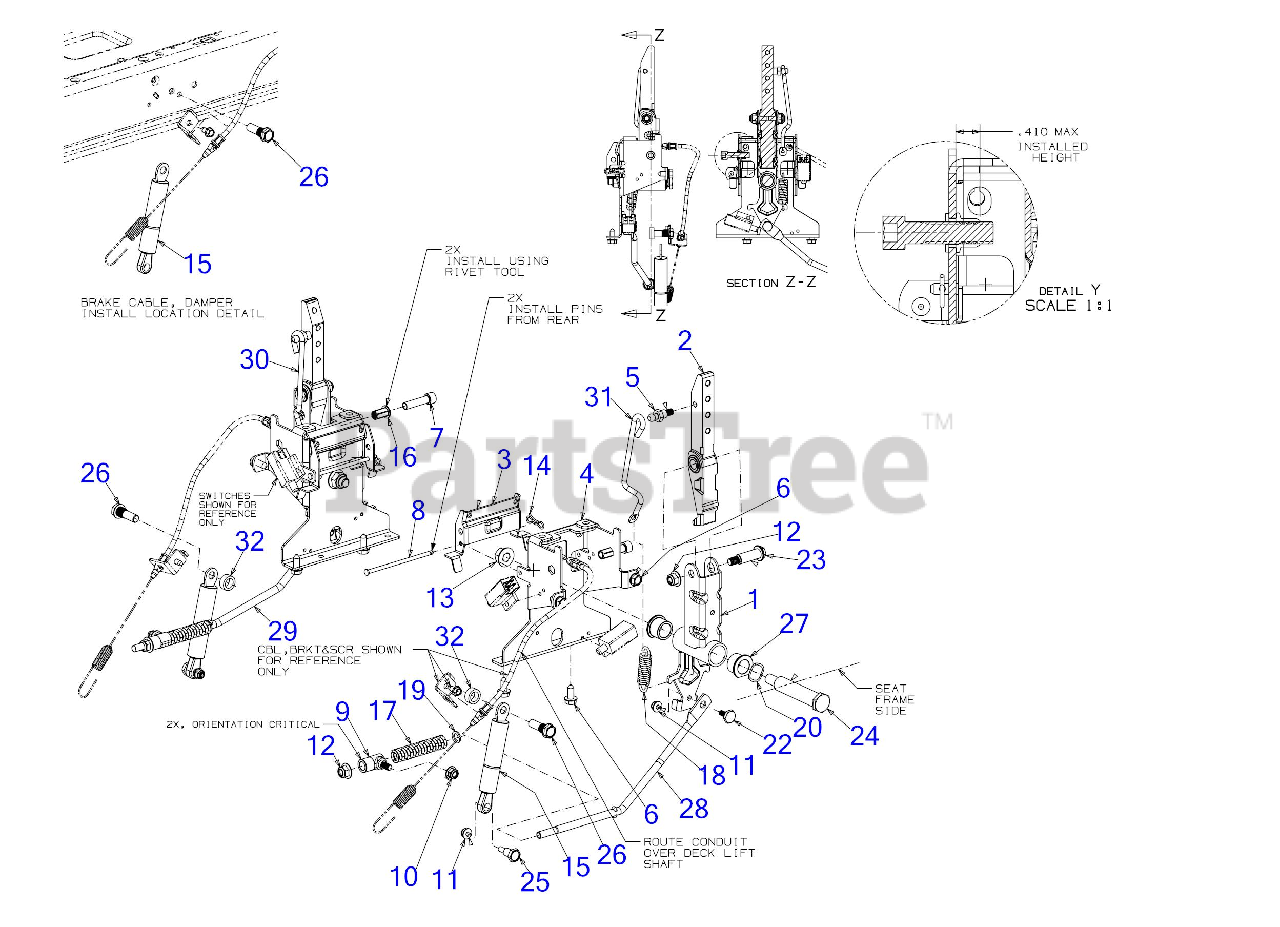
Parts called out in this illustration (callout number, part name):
2	LOWER ARM ASSEMBLY
5	SCREW 5/16-18 x .48
6	SCREW 5/16-18 x .750
7	SCREW 3/8-16 x 1.50
8	PIN .188 x 4.1
9	SHOULDER FERRULE 3/8 ID x .420
10	FLANGE LOCK NUT 5/16-18
11	FLANGE LOCK NUT
14	BOW TIE COTTER PIN 1/4-5/16
15	DAMPNER CYLINDER
16	NUT RIVET
17	COMPRESSION SPRING .690 OD x 3.215 LG
18	EXTENSION SPRING
19	FLAT WASHER
20	WAVE WASHER .785X1.00X.012
22	SHOULDER SCREW
23	SHOULDER BOLT .498 DIA x 1.296 LG
24	SHOULDER BOLT .750 DIA x 3.25 LG
25	SHOULDER BOLT .395 DIA x .56 LG
26	SHOULDER BOLT .395 DIA X.83 LG DOG
27	FLANGE BEARING
28	HYDRO CONTROL ROD (RH)
29	HYDRO CONTROL ROD (LH)
30	LAPBAR DETENT ROD (LH)
31	LAPBAR DETENT ROD (RH)
